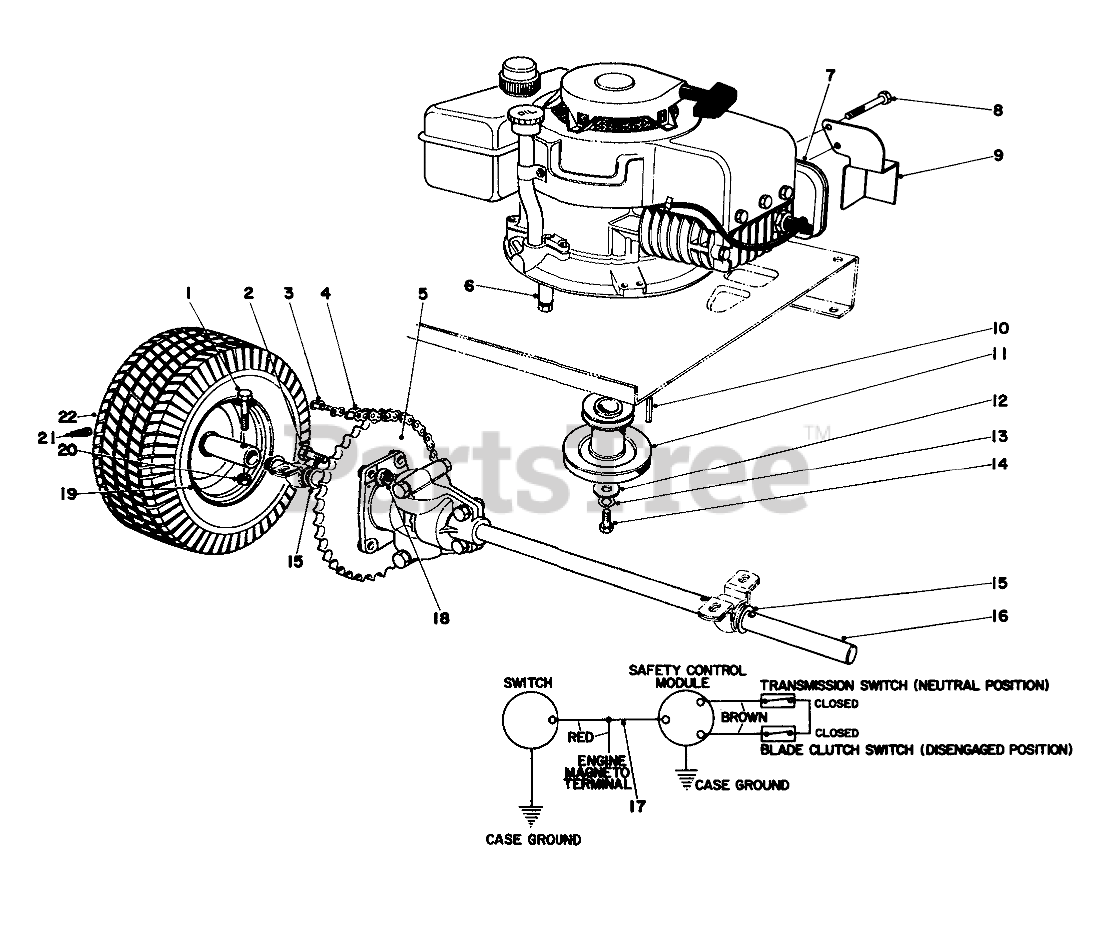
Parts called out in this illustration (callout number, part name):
1	SCREW-HH
2	SCREW-HH
3	LINK-CONNECTING
4	Chain Roller
5	Sprocket
6	Extension Oil Drain
7	Engine
8	SCREW-HH
9	Deflector
11	Pulley
12	Washer
13	WASHER-LOCK
14	Screw
15	DECAL-HOOD R.H.
16	Differential
17	Wiring Harness
18	NUT-LOCK, CONE
20	NUT-LOCK, CONE
21	STEM-VALVE
22	Tire
